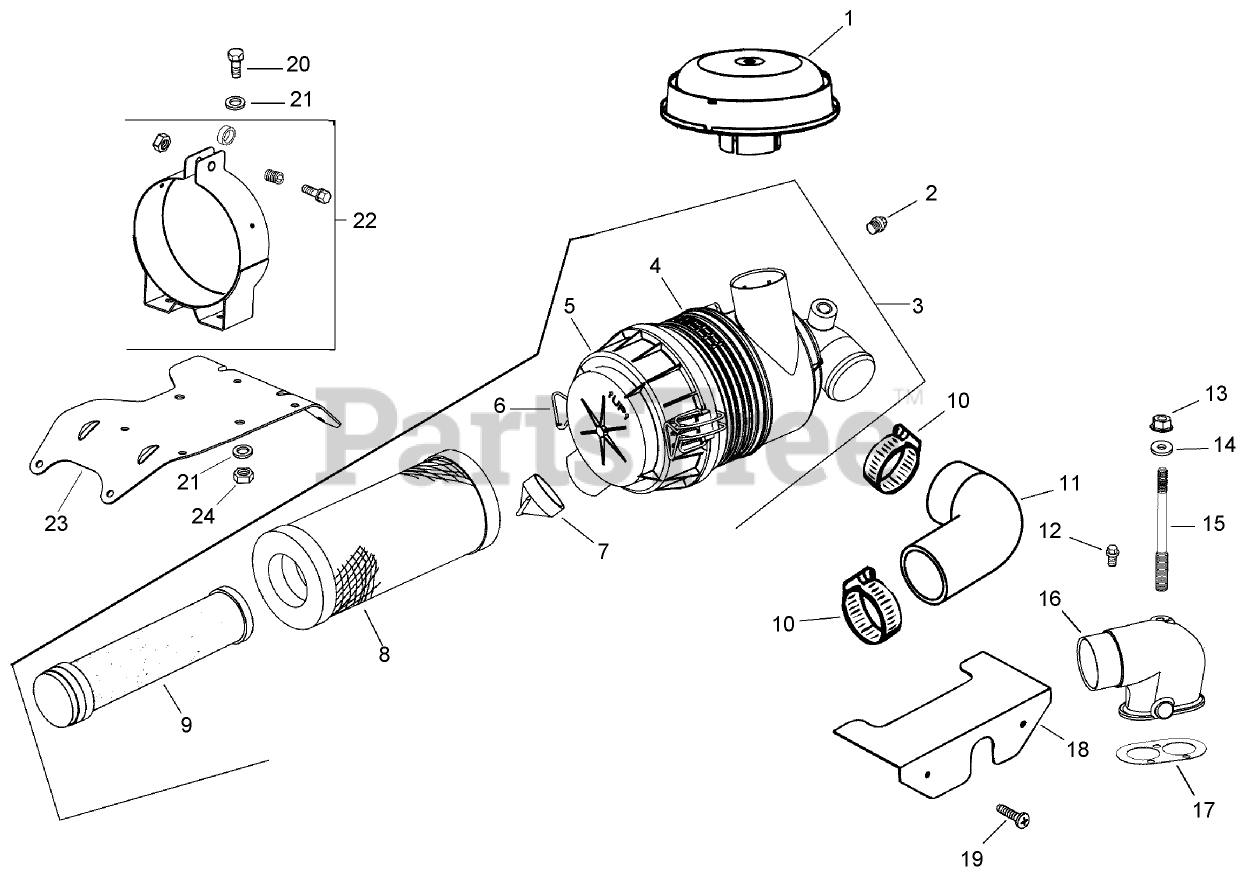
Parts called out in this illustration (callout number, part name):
1	Hood-Cleaner, Air
2	Plug-Pipe
3	Heavy Duty Air Cleaner ASM (Includes 4-9)
4	Housing-Air Cleaner, Heavy Duty
5	Cover ASM (Includes 6, 7)
6	Clip
7	Valve-Ejector, Dust
8	Element-Air Filter, Primary
9	Element-Air Filter, Safety
10	Clamp-Hose
11	Hose-Cleaner, Air
12	Screw-HSH
13	NUT-FLANGE (M6X1.0)
14	Washer-Copper
15	STUD-CARBURETOR (M6X1.0X122)
16	Adapter-Air Cleaner, Remote
17	Gasket-Base, Air Cleaner
18	Shield-Debris
19	SCREW-PPH (11-16X3/4)
20	Screw-HF (M6x1.0x16)
21	Washer-Flat (1/4)
22	Air Cleaner Bracket ASM
23	Bracket-Cleaner, Air
24	Nut-Lock (M6X1.0)
